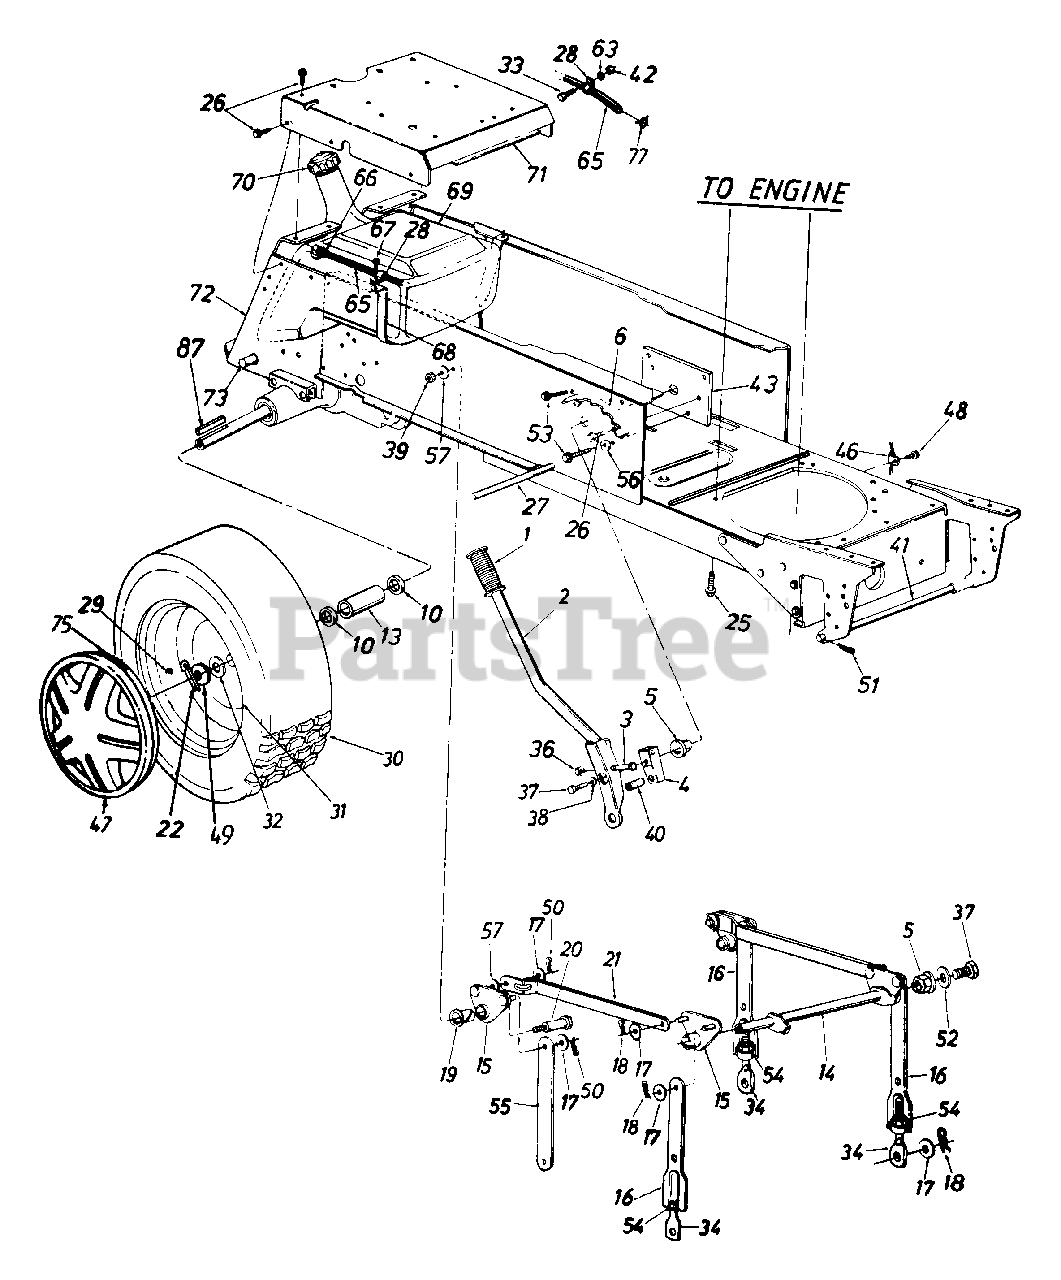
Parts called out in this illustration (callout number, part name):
1	Grip
2	Lift Handle Ass'y.
3	Hex Bolt 5/16-18 x 1.5" Lg.
4	Lift Shaft Drive
5	Plastic Hex Brg. 5/8" I.D.
13	Spacer 1" I.D. x 1.25" O.D.
14	Lift Shaft Ass'y.
15	Lift Pivot Brkt. Ass'y.
17	Fl-Wash. 1/2" I.D. x 1.00" O.D. x .090"
18	Hairpin Cotter
19	Nyliner 5/8" I.D. x .88" Lg.
20	Shld. Bolt 5/8" Dia. x .96" Lg. 3/8-16
25	Hex Wash. Hd. Ser. 3/8-16 x 1.25" Lg.
26	Hex Thd. Rolling Scr. 5/16-18 x .75" Lg.
27	Running Board Rod
28	Clamp
29	Air Valve
33	Hex Bolt 1/4-20 x .62" Lg.
34	Eye Bolt Adj. Link 1/2-13 Thd.
36	Hex Cent. L-Nut 5/16-18 Thd.
37	Hex Bolt 5/16-24 x .62" Lg.
39	Hex Top L-Nut 3/8-16 Thd.
40	Compression Spring
41	Deck Connecting Rod
42	Hex Nut 1/4-20 Thd.
47	Hub Cap
48	Hex Wash. Hd. TT-Tap Scr. 1/4-20 x .5" Lg.
50	Cotter Pin .09 Dia. x 1.0" Lg.
51	Int. Cotter Pin
52	Flat Wash..34" I.O. x 1.12" O.D. x .125"
53	Hex Wash. Hd. AB-Tap Scr. 5/16-24 x .5" Lg.
54	Hex Nut 1/2-13 Thd.
56	Fl-Wash..344" I.D.
57	Bell-Wash..4" I.D. x 1.13" O.D.
63	L-Wash. 1/4" I.D.
65	Fuel Line 46" Lg.
66	Hose Clamp
67	Hex AB-Tap Scr. 1/4 x 62" Lg.
68	Fuel Tank Strap
69	Gas Tank
70	Gas Gauge
75	Spring Clip
77	Hose Clamp
87	Sq. Key 1/4" x 3" Lg.
